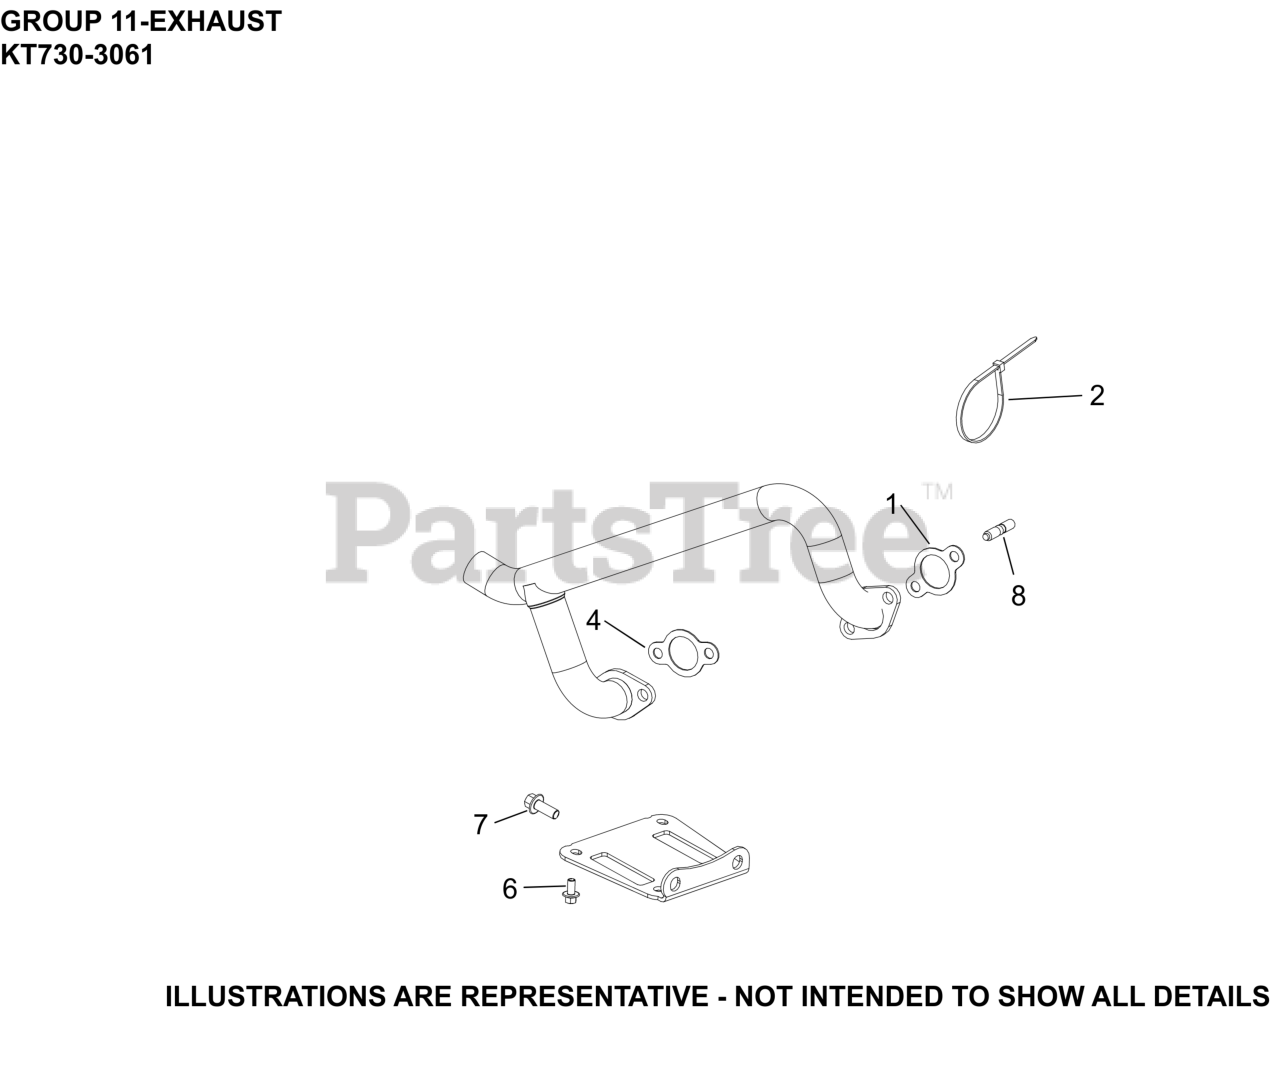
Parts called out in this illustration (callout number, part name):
1	GASKET, EXHAUST MANIFOLD
4	NUT, HEX FLANGE LOCK (M8)
6	SCREW, FLG M6X1.0X12
7	SCREW, FLG M8X1.25X20
8	STUD, METRIC EXHAUST
